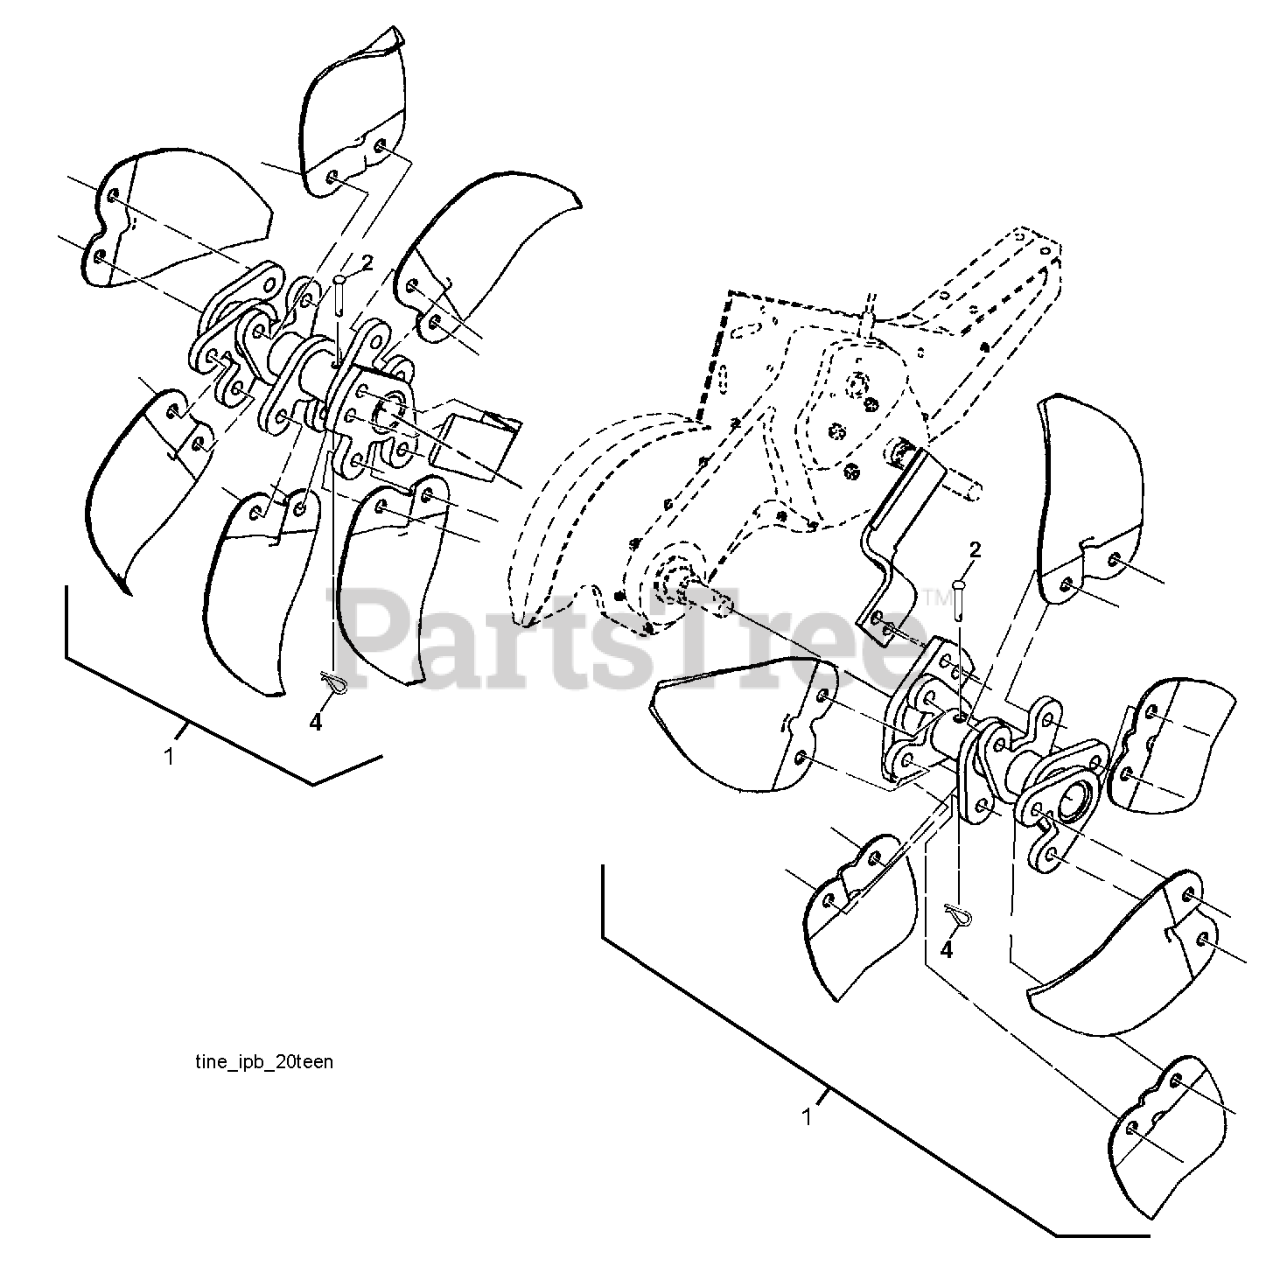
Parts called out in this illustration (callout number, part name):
1	TINE.ASSEM.TILLER.DRT.17.BLACK
2	PIN RETAINING SCREW
4	SPRING RETAINER
